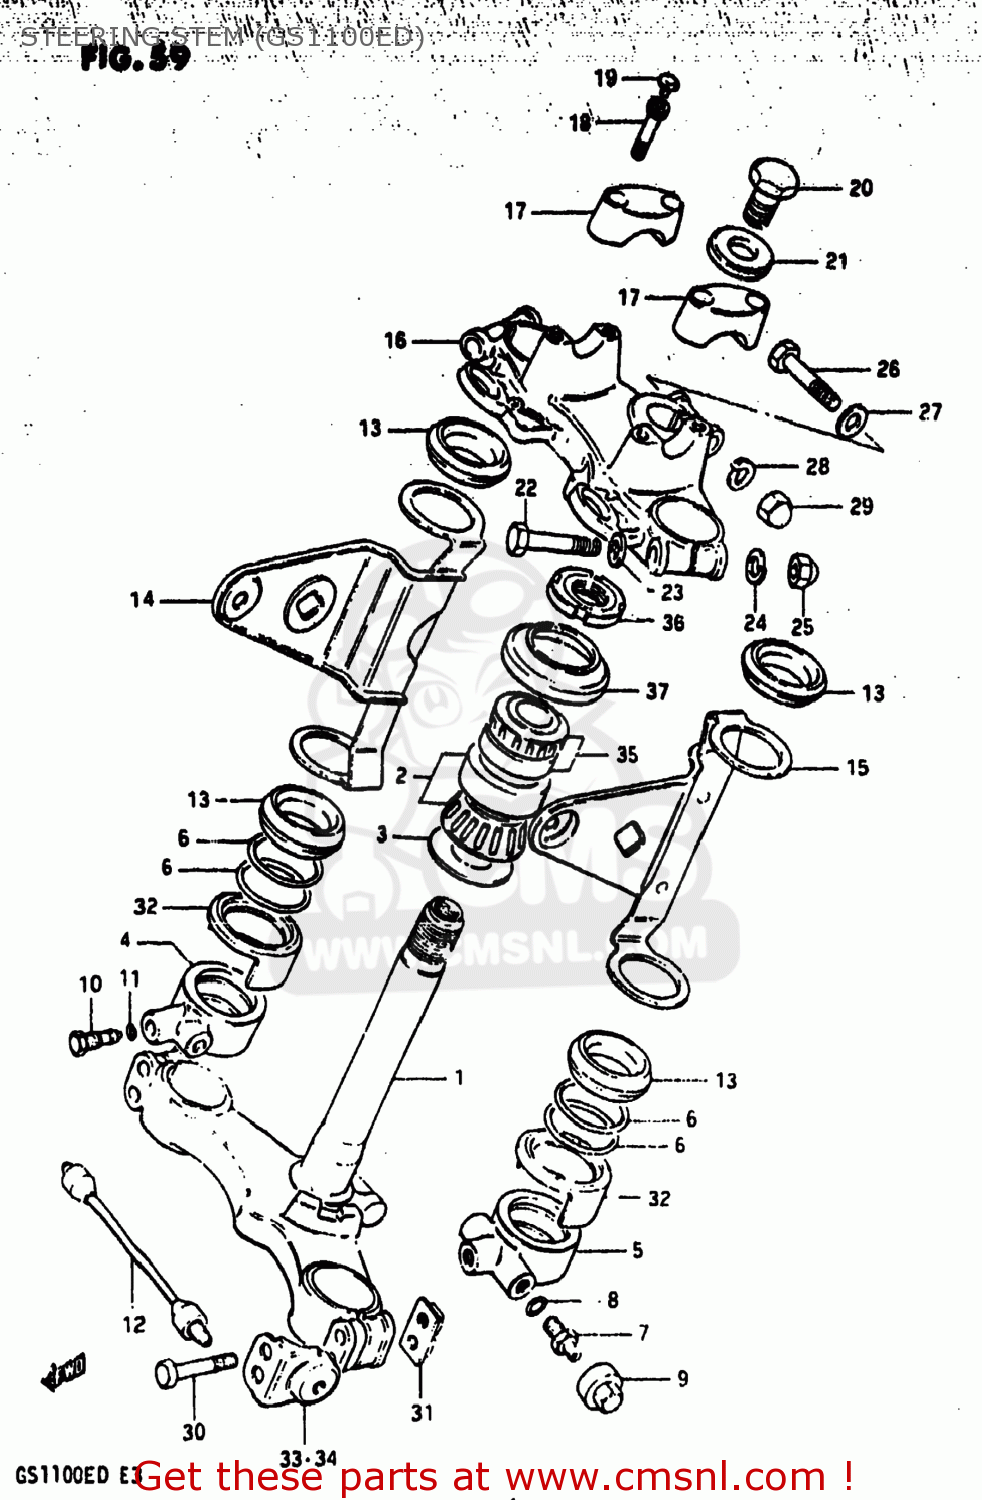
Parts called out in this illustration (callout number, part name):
1	STEM,STEERING
2	BEARING
3	WASHER,THRUST
4	JOINT,AIR,RIGHT
5	BRACKET,FORK CONNECTING
6	O RING
7	VALVE
8	O RING
9	CAP,VALVE
10	VALVE,STOP
11	O RING
12	HOSE,FORK CONNECTING
13	NUT,STEM HEAD
14	BRACKET,HEADLAMP,RIGHT
15	BRACKET,HEADLAMP,LEFT
16	HEAD,STEERING STEM
17	HOLDER,HANDLEBAR
18	BOLT
19	CAP(OD:14.5)
20	SUZUKI
21	SUZUKI
22	BOLT 10X55
23	WASHER
24	LOCK WASHER
25	NUT 10MM
26	BOLT
27	WASHER
28	LOCK WASHER
29	NUT,M8X1.25X12
30	BOLT 8X55
31	NUT,FR FORK INNER TUBE
32	COVER,FORK BRACKET,RIGHT
33	COVER,FORK BRACKET,LEFT
34	BRACKET,REFLECTOR
35	TAPER,ROLLER BEARING
36	NUT,STEERING STEM
37	DUST SEAL,STEERING UPR
